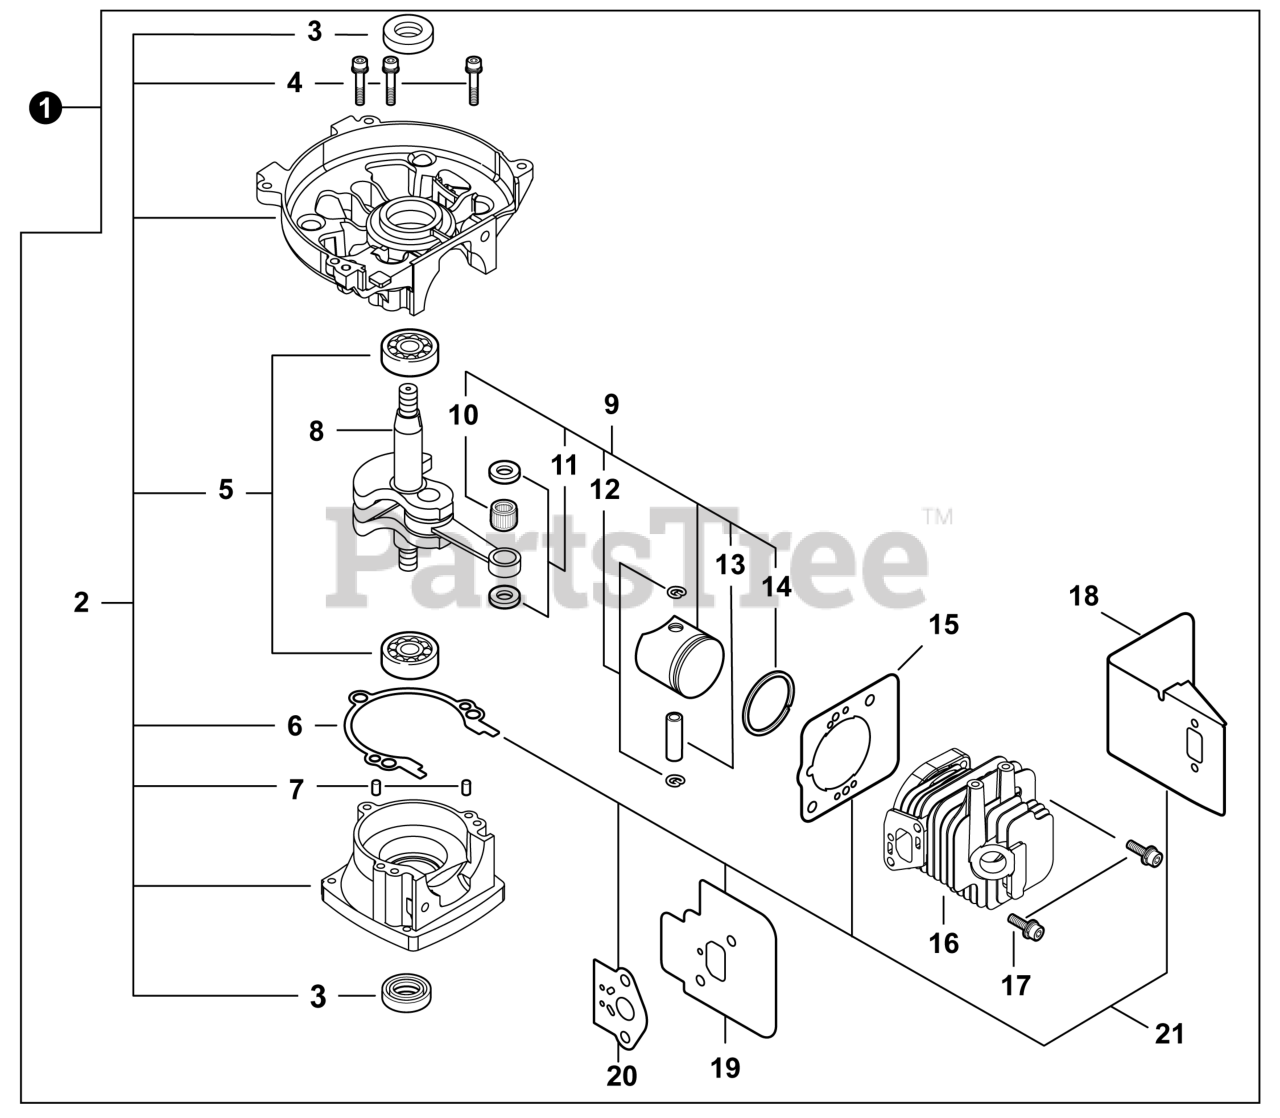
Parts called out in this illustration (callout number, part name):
1	SHORT BLOCK
2	CRANKCASE KIT
3	SEAL, OIL 12
4	BOLT 5×28
5	BEARING, BALL 6201
6	GASKET, CRANKCASE
7	PIN, LOCATING 4×8
8	CRANKSHAFT ASSY
9	PISTON KIT
10	BEARING, NEEDLE
11	WASHER, THRUST
12	RING, SNAP
13	PIN, PISTON 8
14	RING, PISTON
15	GASKET, CYLINDER
16	CYLINDER
17	BOLT 5×22
18	HEAT SHIELD, EXHAUST
19	HEAT SHIELD, INTAKE
20	GASKET, INTAKE
21	GASKET KIT: ENGINE, INTAKE, EXHAUST
